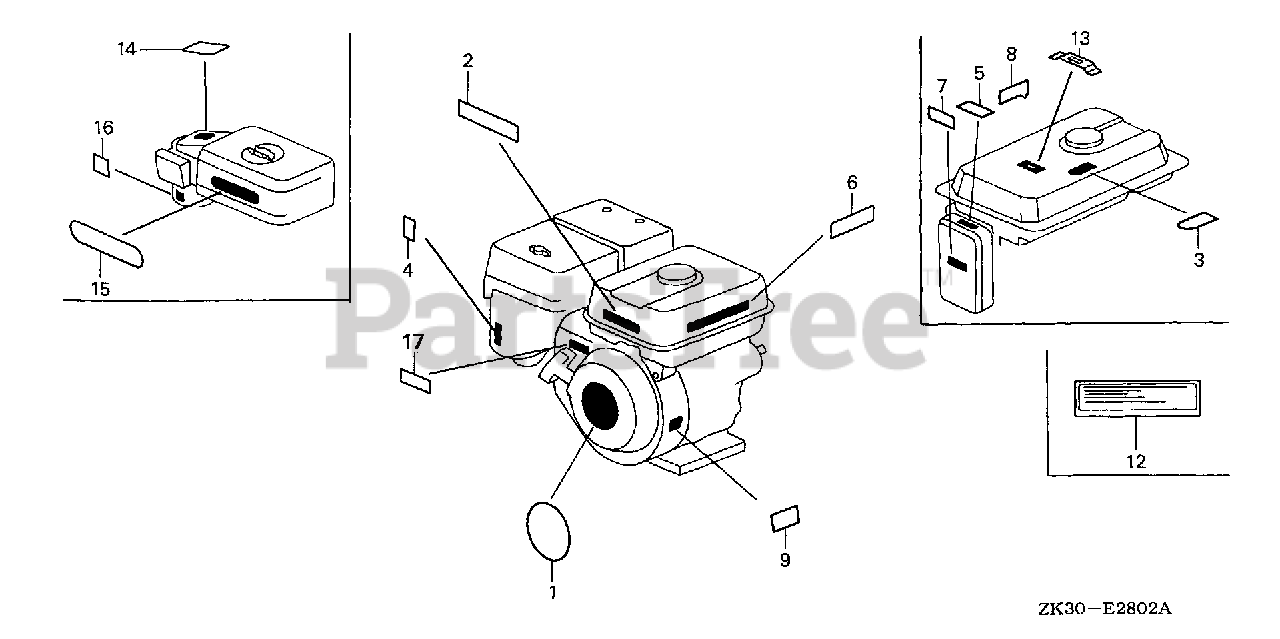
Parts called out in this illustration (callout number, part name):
1	EMBLEM (11. (HONDA)
1	EMBLEM (GX340)
2	LABEL, CAUTION (ENGLISH, ETC.)
4	MARK, CHOKE (ORANGE)
6	MARK, OIL ALERT (ENGLISH)
9	MARK, OIL ALERT (ENGLISH)
14	LABEL, AIR CLEANER CAUTION
15	MARK, AIR CLEANER SALES POINT
16	MARK, CHOKE (ORANGE)
